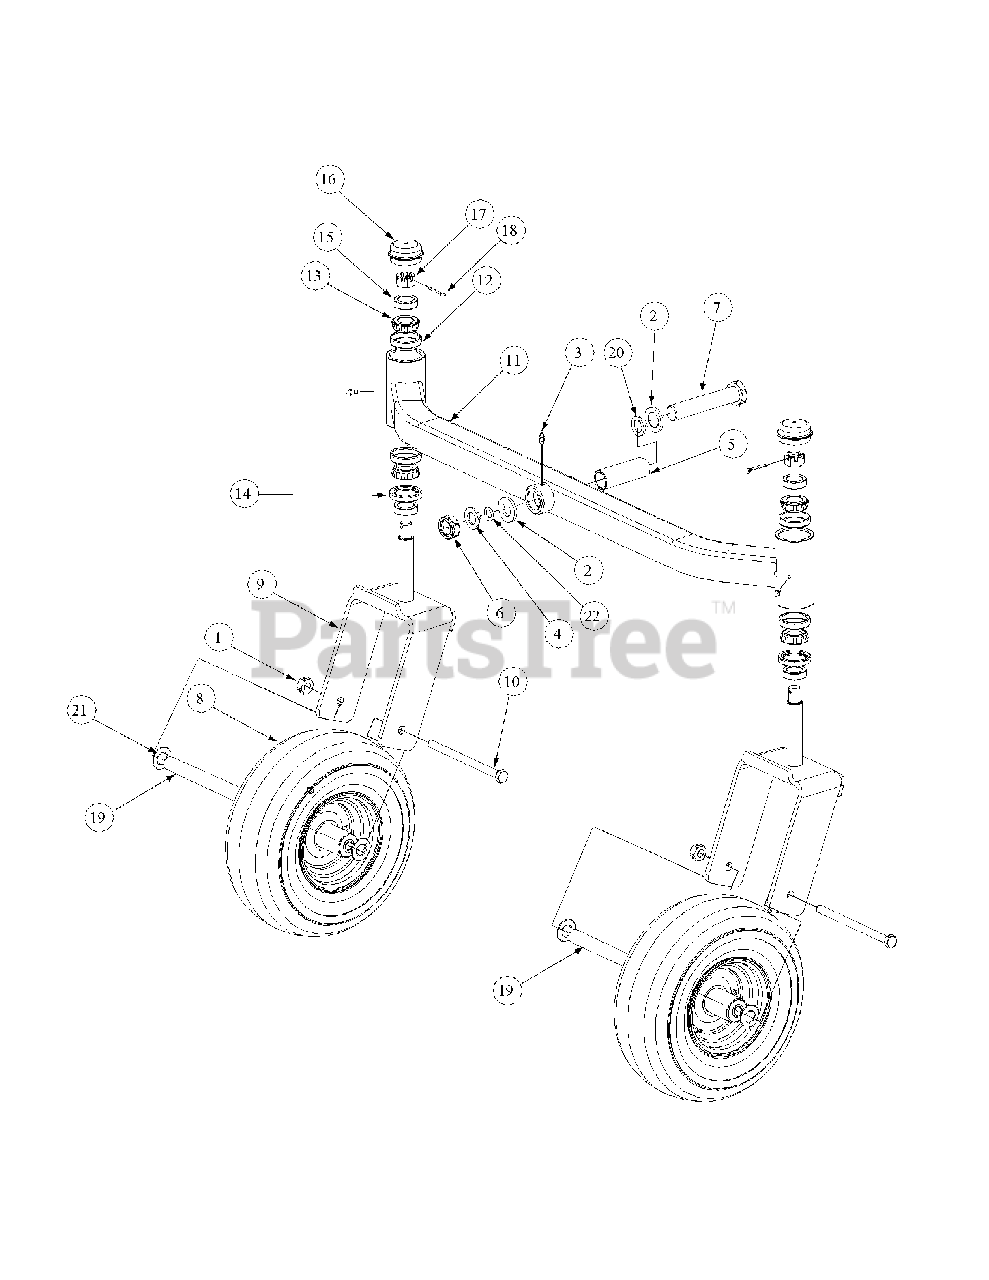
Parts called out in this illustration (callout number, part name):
1	Nut, 1/2-20, Center Lock
2	Bell Washer, 1.25 ID x 2.5 x .157
3	Grease Fitting, 1/4-28 x 3/16
4	Special Washer
5	Spacer, 1.005 ID x 1.25 OD x 3.6
6	Nut, Jam, 1.0-14, Insert Lock
7	Hex Cap Screw, 1-14 x 5.0
8	Wheel Assembly, 13 x 6.50 x 6, White includes:
9	Yoke, Caster Wheel
10	HHCS, 1/2-20, 7.50
11	Front Axle Assembly
12	Cup Bearing
13	Bearing Cone
14	Seal
15	Ring Seal
16	Grease Cap, 1.986 OD
17	Slotted Nut, 3/4-16
18	Cotter Pin, 5/32, 1.25
19	Wheel Spacer
20	Flat Washer, 1.25 ID
21	Spacer, .812 ID x .218LG
22	Retainer Extension, Self Locking
